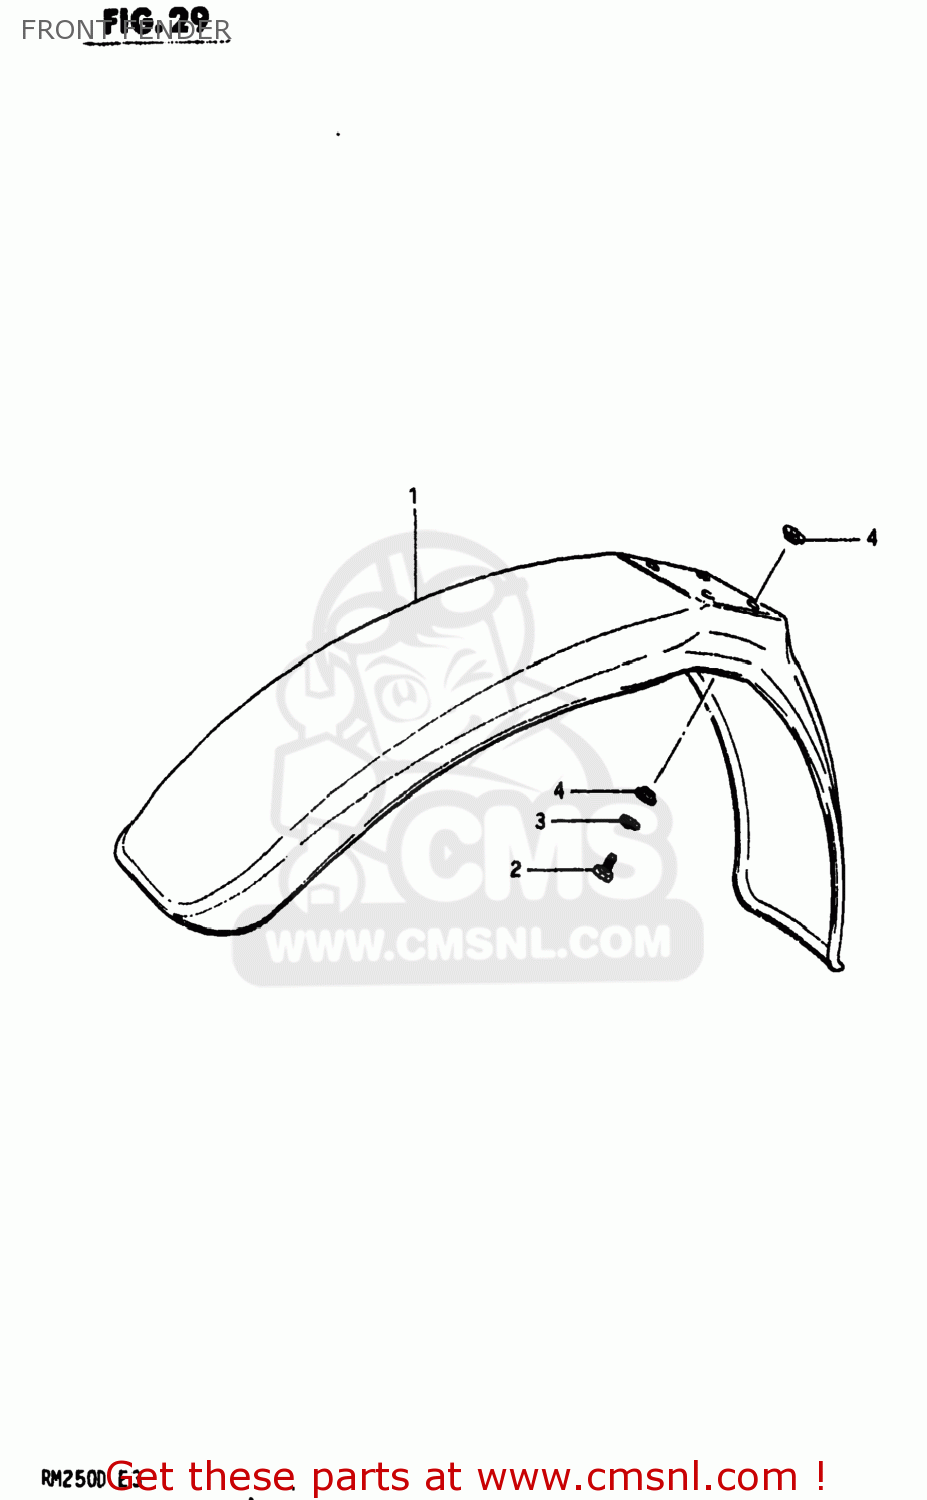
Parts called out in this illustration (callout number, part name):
1	FENDER,FR
2	BOLT, UPPER
3	LOCK WASHER
4	SPACER
